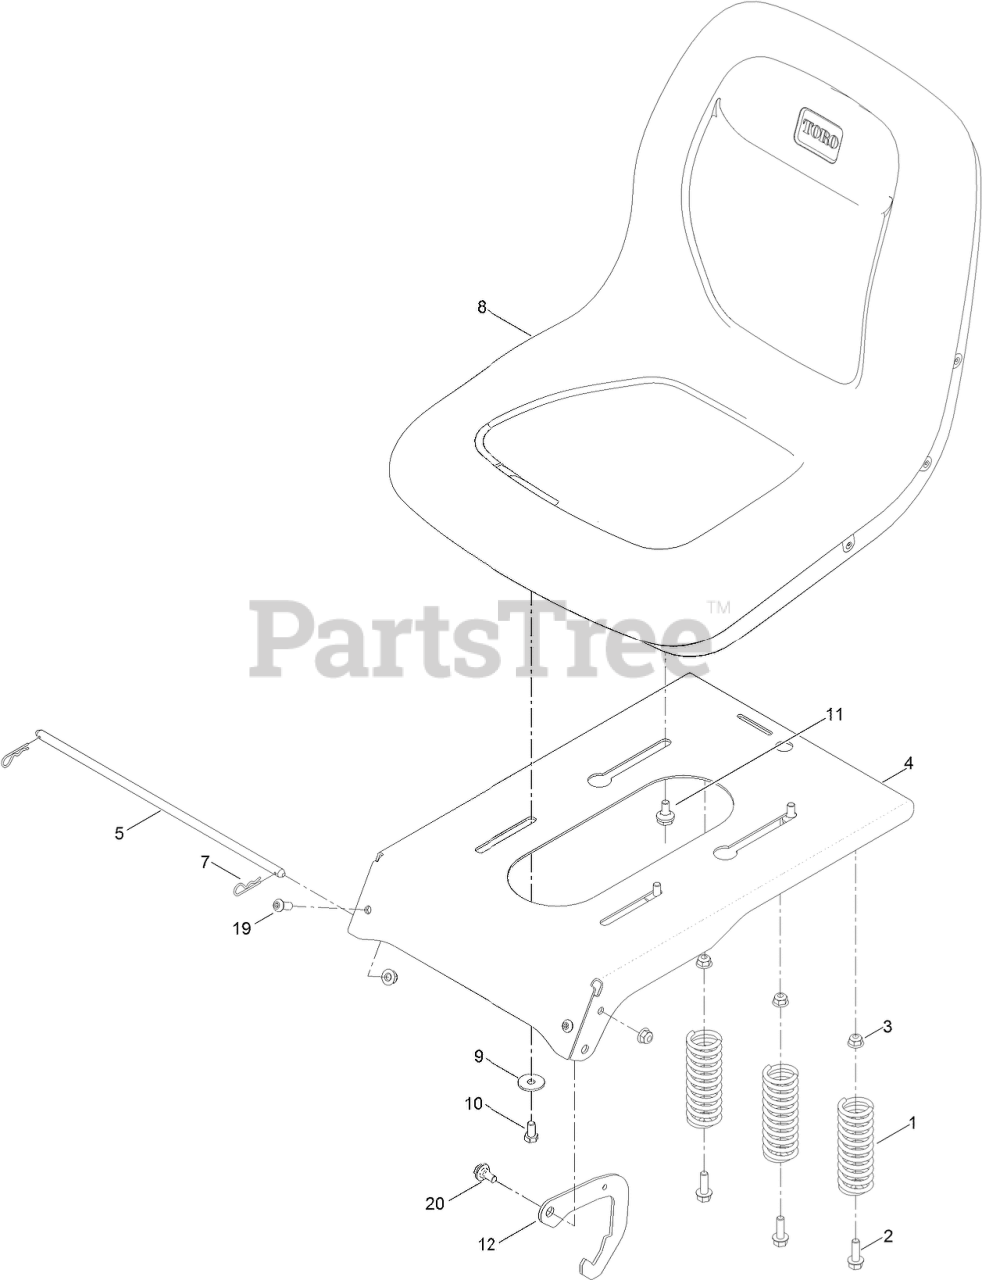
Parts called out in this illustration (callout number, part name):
1	SPRING-COMPRESSION
2	SCREW-HHF
3	NUT-HF, NI
4	PAN-SEAT
5	ROD-PIVOT, NARROW
7	PIN-COTTER
8	SEAT-18 INCH
9	WASHER-PIVOT
10	SCREW-HH
11	BOLT-SHOULDER
12	LATCH-SEAT
19	SCREW-HSBH
20	SCREW-SHOULDER
